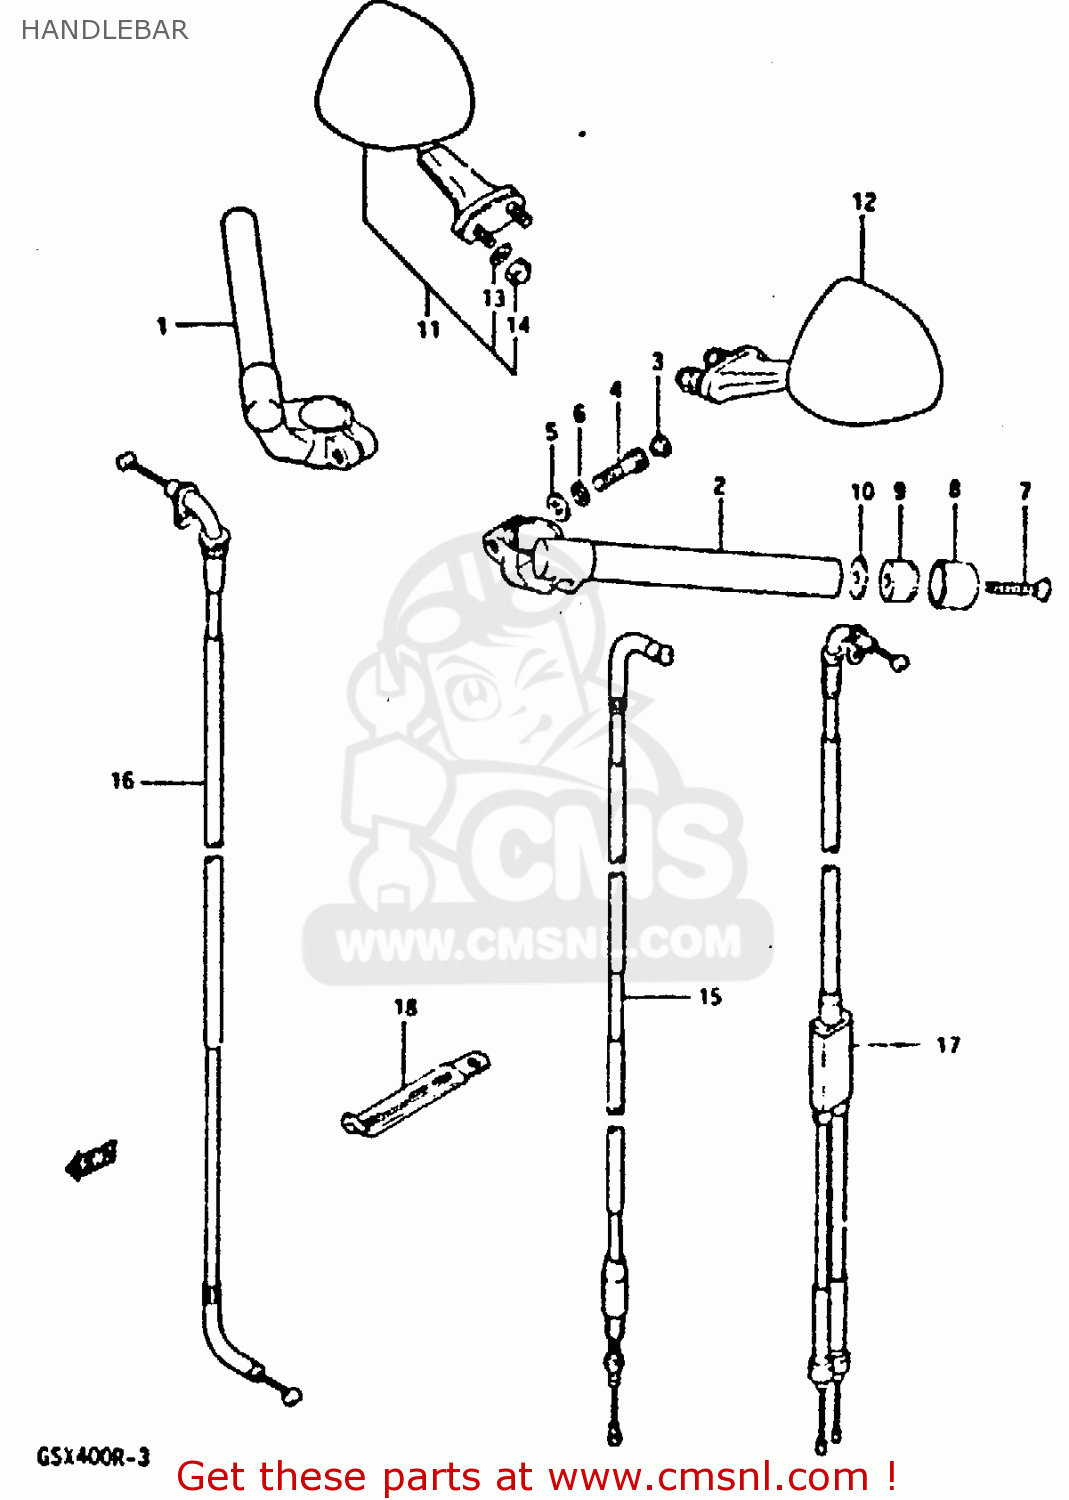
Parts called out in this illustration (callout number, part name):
3	CAP
4	BOLT, RH
5	WASHER
6	LOCK WASHER
7	SCREW
8	CAP,HANDLE BALANCER
9	BALANCER,HANDLEBAR
10	SPACER,BALANCER
11	MIRROR ASSY,RR VIEW,R
12	SPIEGELSET.L
13	WASHER
14	NUT 6MM
15	CABLE .CLUTCH
16	CABLE ASSY,THROTTLE
17	CABLE,STARTER
18	CLAMP
